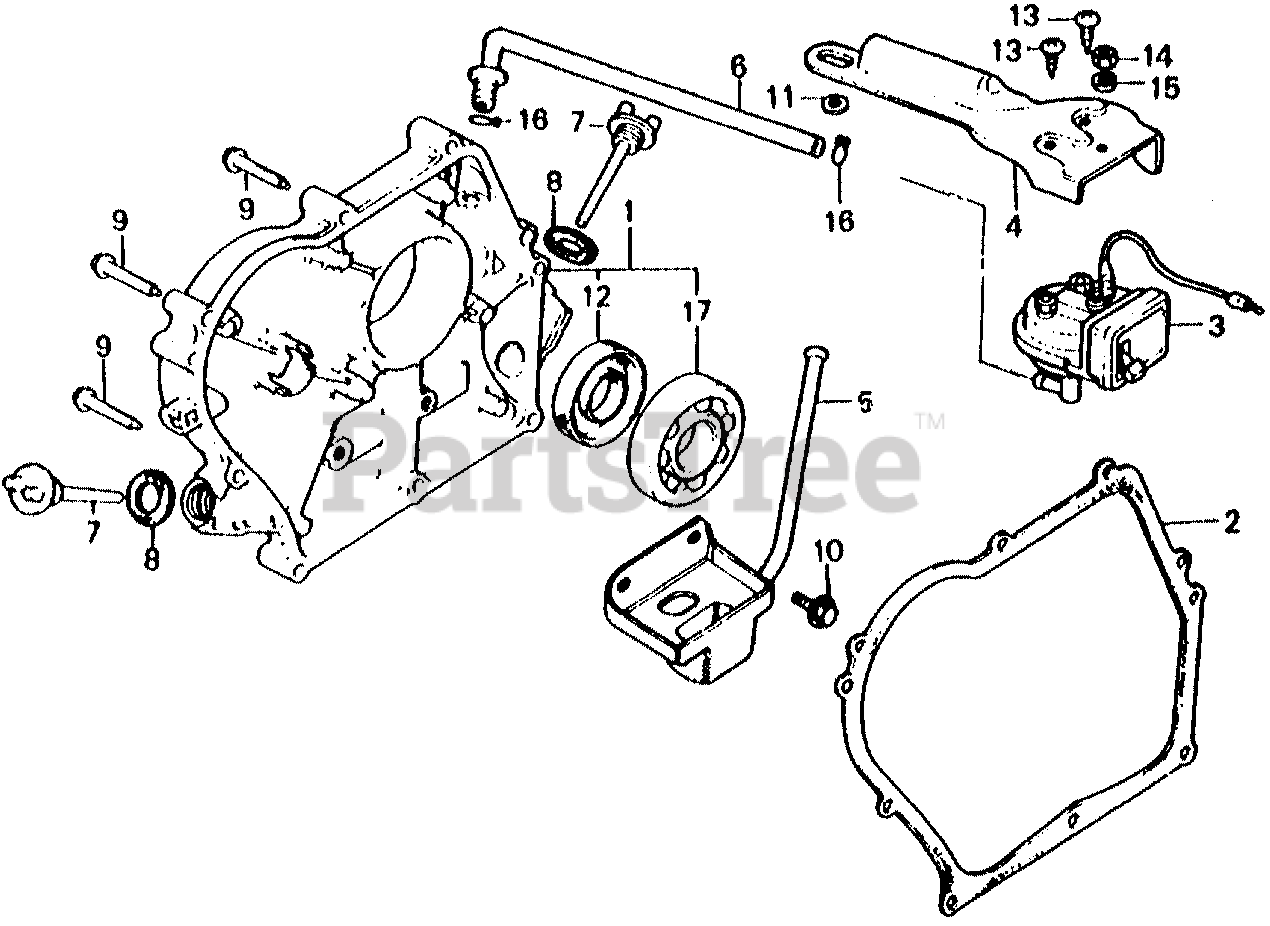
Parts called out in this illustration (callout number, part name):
1	COVER ASSY., CRANKCASE (EDZ-TYPE)
2	GASKET, COVER
3	SWITCH ASSY., UNIT
4	BRACKET, UNIT SWITCH
5	CUP, OIL
6	TUBE, OIL ALERT
7	CAP, OIL
8	GASKET, OIL FILLER CAP
9	BOLT, FLANGE (6X32)
10	BOLT, FLANGE (6X16)
11	WASHER (18MM)
12	OIL SEAL (25X41X6)
13	SCREW, TAPPING (5X10)
14	NUT, HEX. (5MM)
15	WASHER, SPRING (5MM)
16	CLIP, TUBE (C11)
17	BEARING, RADIAL BALL (6205)
